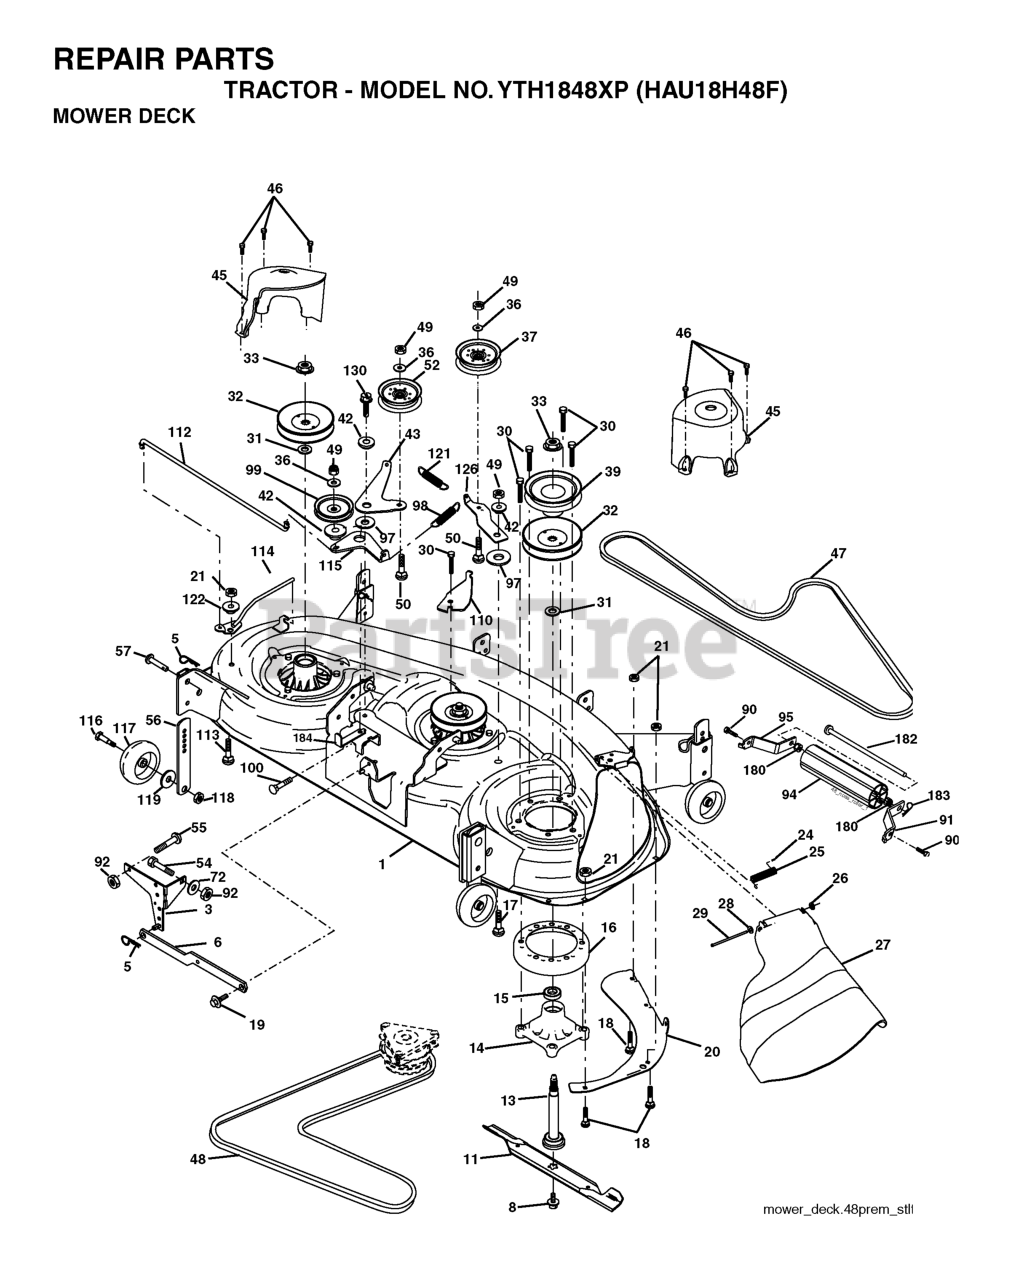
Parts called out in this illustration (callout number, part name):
1	DECK WELDMENT MOWER, 48
3	BRKT ASM SWAY BAR
5	RETAINER-SPRNG RB
6	BAR SWAY DECK
8	BOLT 7/16 ASM BLADE
11	48" HI-LIFT BLADE
13	SHAFT ASM W/LOWER BEARING
14	HOUSING, MANDREL 48"
16	STRIPPER.MANDREL.ROUND.BLACK
17	BOLT
18	BOLT
19	BOLT SHD 5/16-18
20	BAFFLE, VORTEX MWR
21	LOCKNUT
24	CAP-SLEEVE LT
25	SPRING, TORSION
26	NUT PUSH M
27	DEFLECTOR SUBS TO 532 180655
28	Washer 11/32 x 5/8 x 16 Ga SD
29	ROD.HINGE
30	SCREW, WASHER HEAD
31	WASHER
32	PULLEY, MANDREL
33	NUT, FLG TOPLOCK 9/16"
36	WASHER
37	PULLEY.IDLER.FLAT
39	PULLEY.DRIVEN.DECK.48'
42	SPACER RETAINER
43	ARM, IDLER SECONDARY
45	COVER.MANDREL.DECK.48"
46	SCREW.1/4-20X5/8
47	V-BELT, 48"SECONDARY
48	V-BELT PRIMARY 48"
50	BOLT.3/8-16X1.50
52	PULLEY.IDLER.FLAT.46.PR.DR.
54	BOLT
55	BOLT D
56	BAR.ADJUST.WHEEL.ANTI.SCALP.BL
57	RIVET.PIN.HEAD.YELLOW.
72	WASHER
90	BOLT RB
91	BRKT.NOSEROLLER.RH.48"
92	NUT
94	NOSE ROLLER 48"
95	BRKT.NOSEROLLER.LH.48"
98	SPRING PRIMARY DRIVE
99	IDLER PULLEY
100	BOLT
110	ARM, SPRING SECONDARY
112	LEVER, TENSION RELIEF LINK
113	BOLT.CARR.SQNK.5/16-18UNC.X3/4
114	LEVER ASM, TENSION RELIEF
115	ARM, SPRING TENSION RELIEF
116	SHOULDER BOLT
117	WHEEL GAGE DONUT
118	LOCKNUT
119	WASHER.5/16.FLAT.STE.STD.
121	SPRING.DRIVE.SECONDARY.48".DEC
122	BUSHING, PIVOT TENSION RELIEF
126	ARM, IDLER PRIMARY DECK
130	SCREW 3/8-16X1
180	NUT.71038.31-18.HEX.NYLOCK
182	ROD.ROLLER.NOSE.NARROW.48"
183	SPRING RETAINER
184	KEEPER BELT IDLER PLATED
